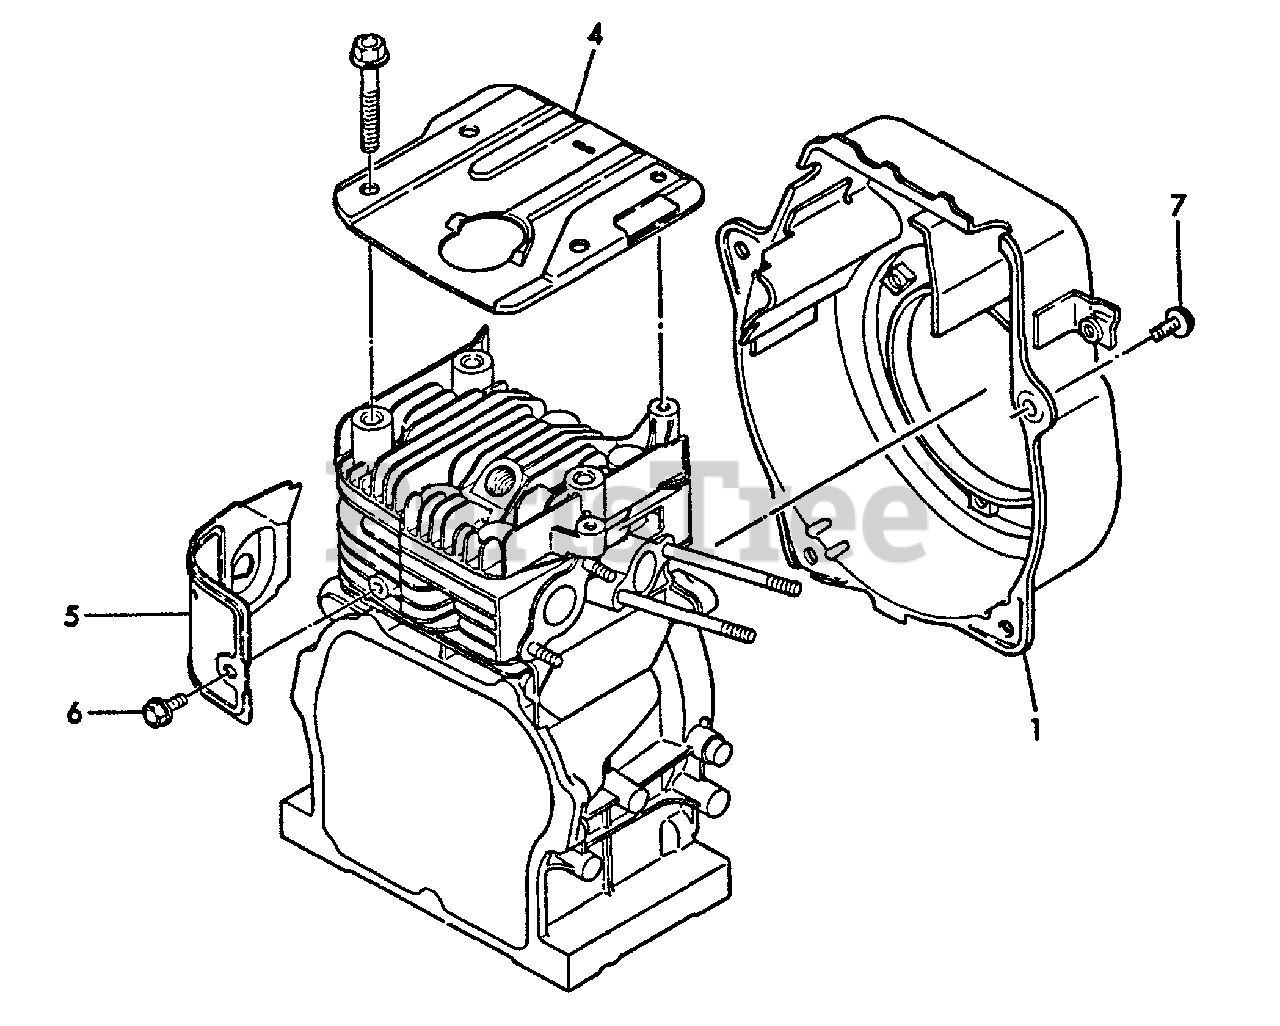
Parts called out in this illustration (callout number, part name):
1	COVER, FAN
4	COVER, CYLINDER HEAD
5	SHIELD, CYLINDER
6	BOLT - 6×8 -- PLATED
7	BOLT - 6×8 -- PLATED
